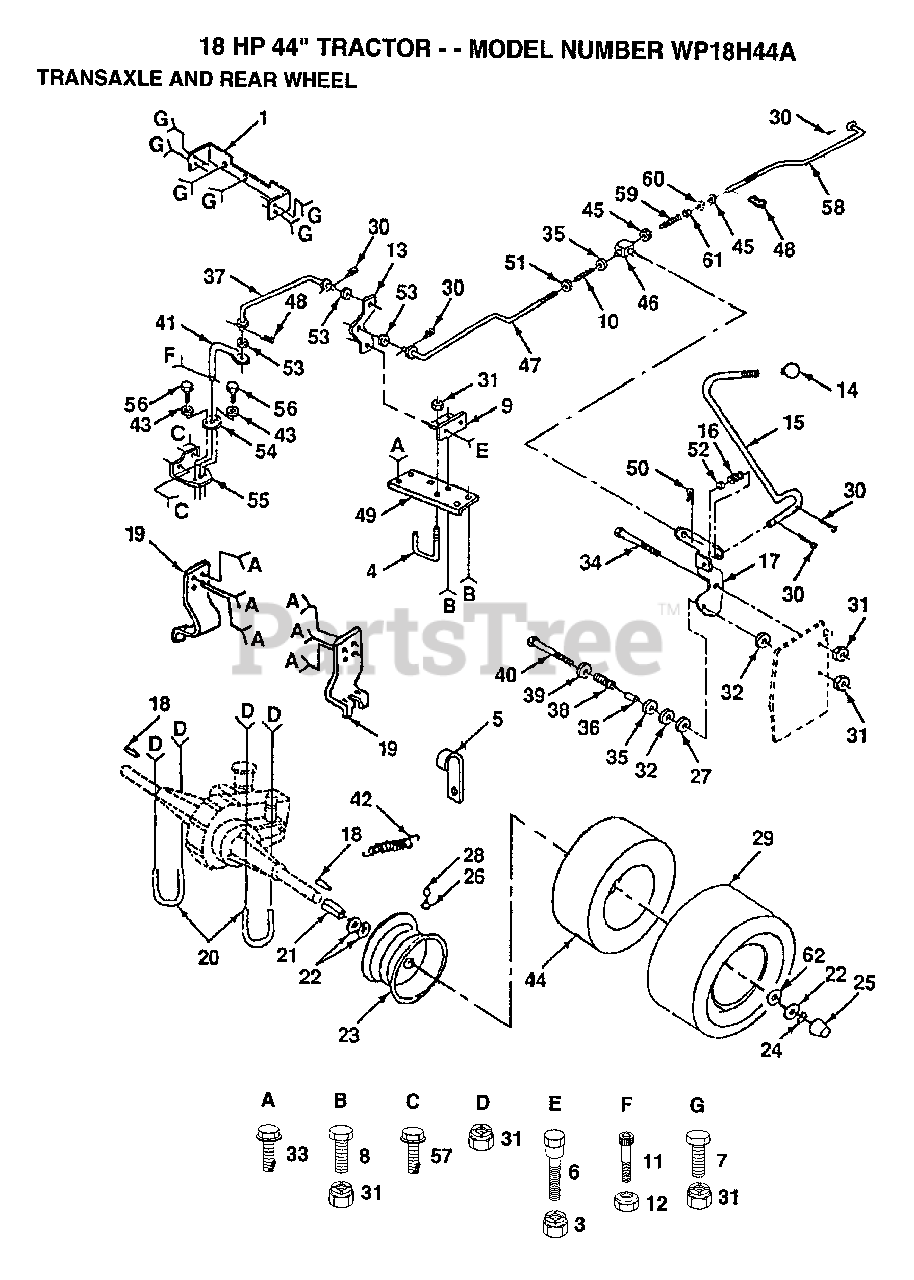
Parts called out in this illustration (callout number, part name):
1	PLATE TRANS SUPT
2	TRANSAXLE.AGRIFAB
4	KEEPER
5	CLIP T
6	SHOULDER BOLT LT
8	BOLT
9	BRKT BELLCRANK
10	SPRING GTV
11	SCREW
12	LOCKNUT
13	BELLCRANK
14	KNOB.DUCKHEAD.1/2
15	ROD.YTH
16	SPRING TORSION
17	BRKT CONTROL HYT
18	SQUARE KEY
19	BRKT TRANSAXLE
20	U BOLT
21	SPACER SPLIT
22	WASHER
24	E-RING LT
25	HUB CAP
26	VALVE STEM LT
27	WASHER HYT
28	VALVE CAP
30	COTTER PIN
32	WASHER FRIC HYT
33	SCREW
34	BOLT HYT
35	WASHER D
36	SPACER HYT
37	LINK CONTROL
38	SPRING HYT
39	WASHER
40	BOLT - HEX 3/8 - 16 X 3
41	ARM ASM PUMP
43	WASHER
44	TUBE.18X9.5-8
45	NUT
46	TRUNION HYT
47	ROD ADJ CONTROL
48	RETAINER M
49	BRACKET
50	SPRING.RETAINER
51	WASHER T
52	WASHER
53	WASHER T
54	GUIDE CONTROL
55	BRKT
57	SCREW
59	SPRING ROD LT
60	WASHER
61	NUT
62	WASHER
